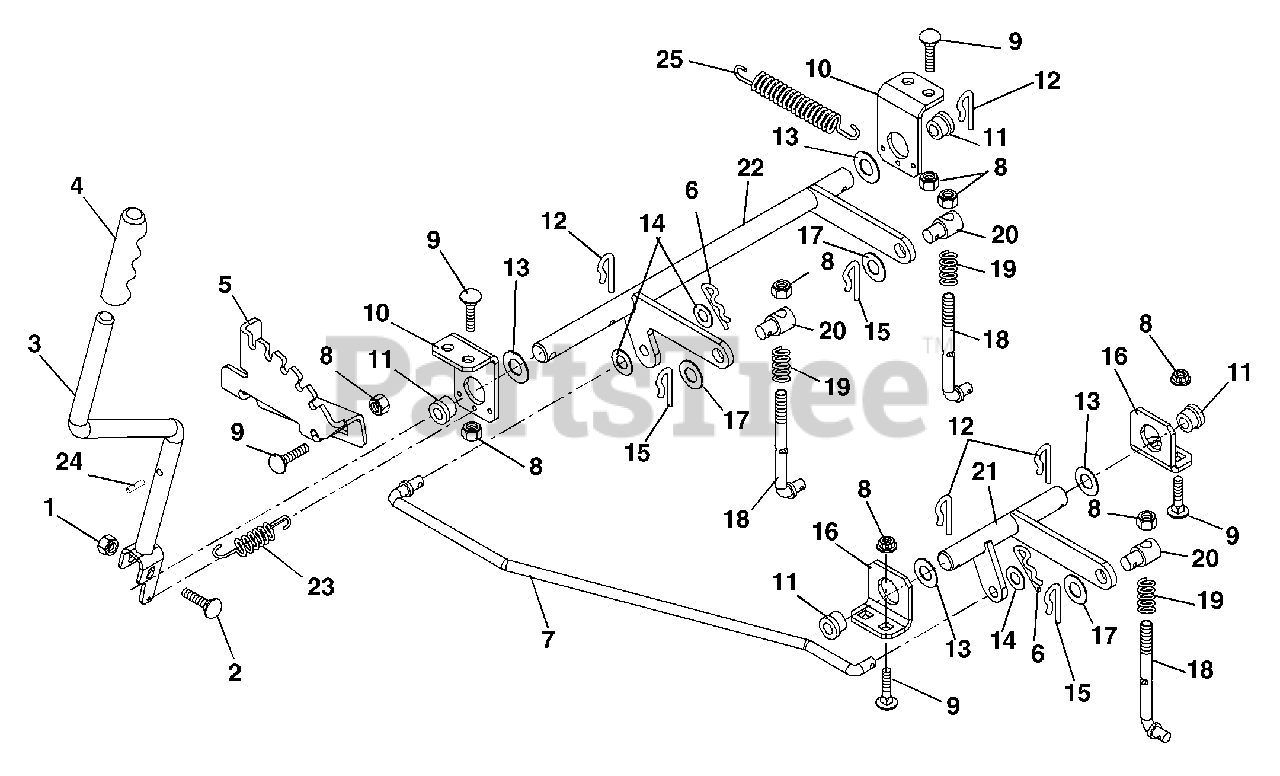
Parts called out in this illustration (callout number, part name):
1	Nut-Locking-Top-Flange .31-18
2	Bolt-Round Head Square Neck .31-18 x 1.50 Grade 5
3	Weldment-Lift Handle
5	Detent Plate
6	Pin, Hair
7	Lift Link
8	Nut-Locking-Top-Flange .38-16
9	Bolt-Round Head Square Neck .38-16 x .75 Grade 5
10	Bracket, Lift
11	Bushing-Flange .75 x 1.00 x .625 x 1.25
12	Pin, Spring Clip
13	Washer, Flat Steel .563 x 1.38 x .109
14	Washer, Flat Steel .406 x .812 x .065
15	Clip, Spring
16	Bracket, Deck Pivot
17	Washer, Flat Steel .505 x 1.00 x .062
18	Rod, Link
19	Spring-Compression .063 x .53 x 1.187
20	Trunnion
21	Weldment, Front Lift
22	Weldment, Lift
23	Spring, Extension
24	Pin-Roll .125 x 1.00
25	Spring-Tension .08 x .687 x 5.16
